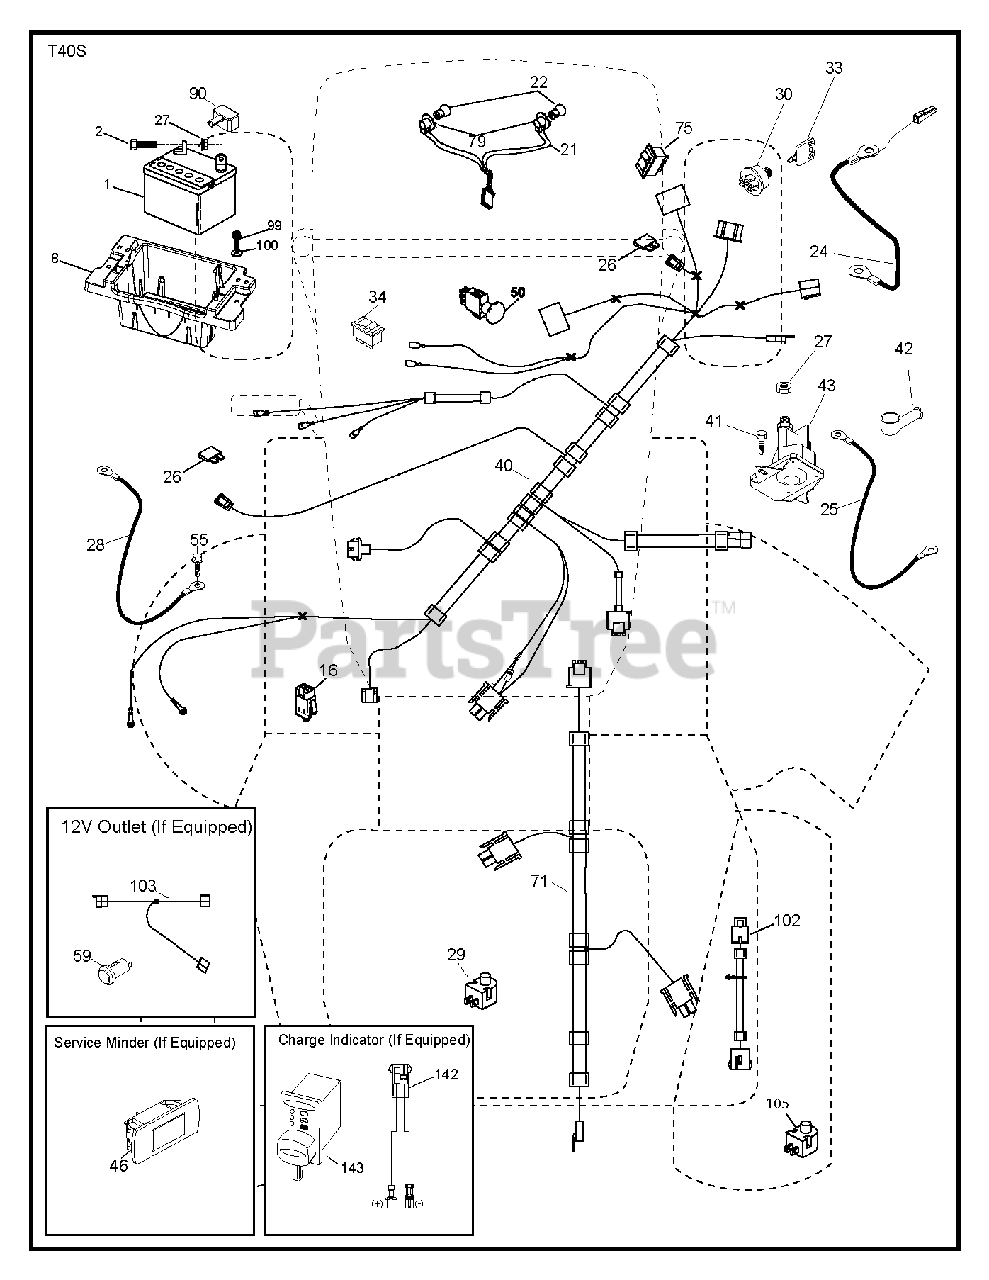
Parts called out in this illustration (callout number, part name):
1	Battery, Dry 30 Amp
2	BOLT.HEX.1/4.X.3/4.DICHROMATE
8	TRAY.ASM.BATTERY.FRT.TEX.CARB
16	SWITCH INTERLOOK PUSH-IN
21	HARNESS.LIGHT W/4152J BULBS
24	CABLE.FRBATT.W/WIRE.8GA.8
25	CABLE.STARTER.8GA.17.5
26	FUSE 20AMP
27	NUT
28	CABLE.GROUND.21"BLK.8GA.90T
29	SWITCH.SEAT.DP W/RAMPS
30	SWITCH.IGN.DELTA.W.LGH.ROS
33	KEY.CHAIN.BLISTER.PACK.GEN.USA
40	HARNESS DASH DIFF LOCK HARNESS
41	SCREW
42	TERMINAL COVER
43	SOLENOID.STARTER.BRASS.PLUNGER
46	GUAGE.SRVCMNDR.HRMTR.
50	SWITCH.PTO.8TERMINAL.STD.BLK
55	SCREW 5/16"
71	HARNESS.IGN.CHASSIS.TEX.DCKLOC
75	SWITCH.ON/OFF.(DIFF.LOCK)
79	BULB HOLDER ASM.
90	COVER.TERMINAL.BATTERY
99	SCREW HEXWSHR 1/4-20X3/4
102	HARNESS PIGTAIL PCH TEX ROS
105	REVERSE SWITCH
